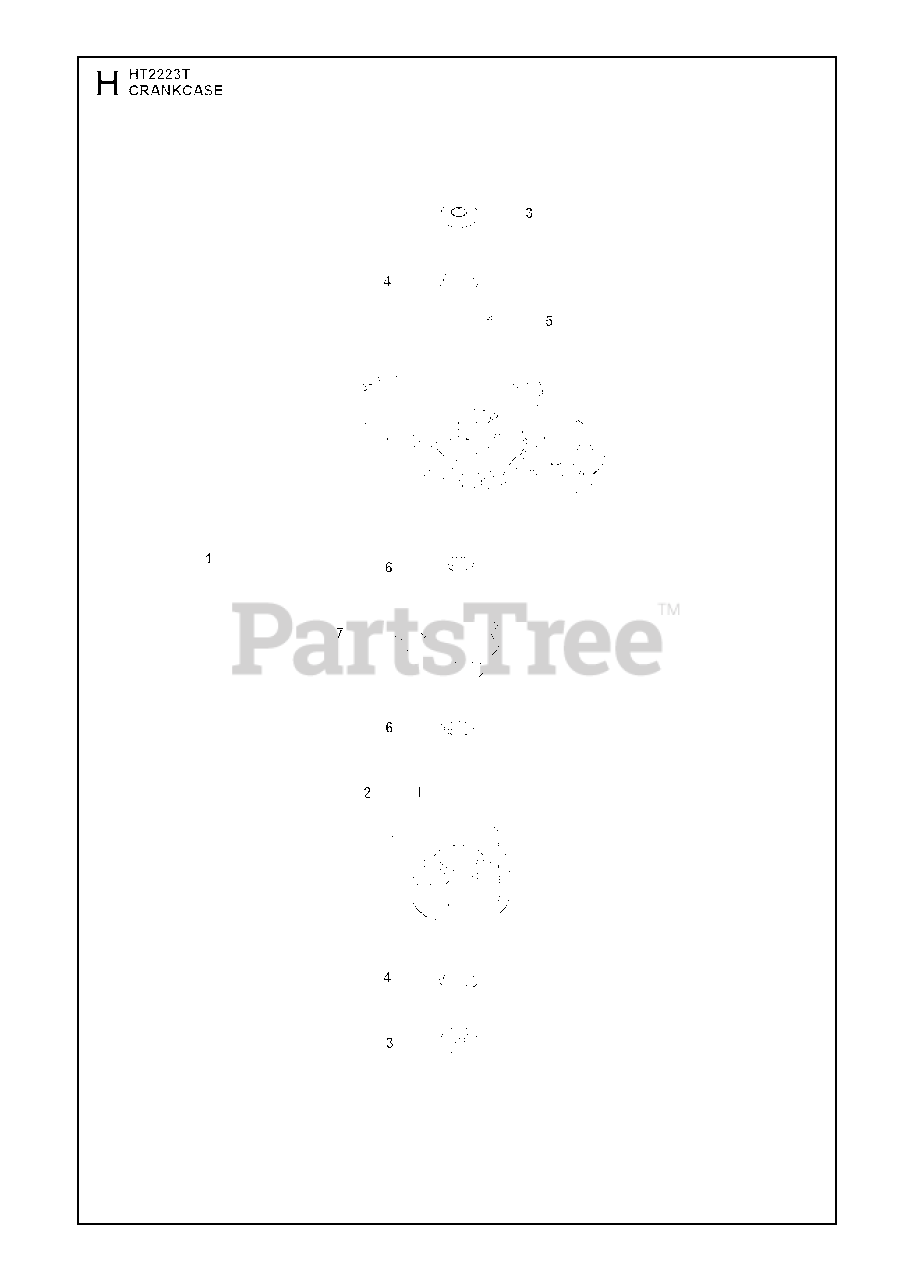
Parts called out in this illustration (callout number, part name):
1	CRANKCASE
2	PIN
3	SEALING RING
4	RETAINING RING SGH 26
5	SCREW
6	BALL BEARING
7	GASKET
